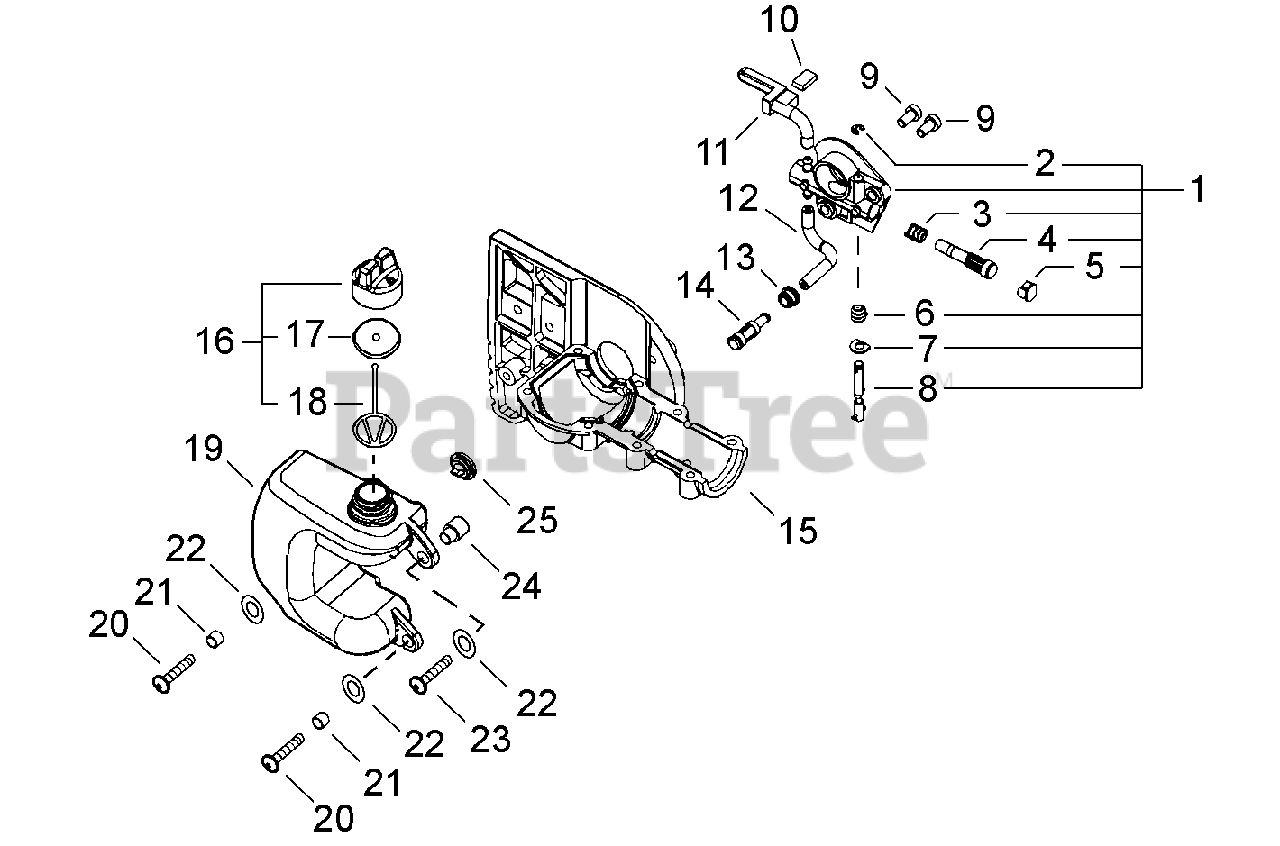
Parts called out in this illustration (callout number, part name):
1	AUTO-OILER ASSY
4	PLUNGER ASSY
5	CAP, OIL PUMP
8	ADJUSTER, OILER
9	BOLT 5×10
10	PAD, FOAM
11	PIPE, OIL OUTLET
12	PIPE, IMPULSE 3×6×75
13	GROMMET
14	FILTER, OIL
15	CASE ASSY, LOWER GEAR
16	CAP ASSY, OIL
17	GASKET, CAP
18	CONNECTOR, CAP L= 60 MM
19	TANK, OIL
20	BOLT 5×16
21	SPACER 6.2×7.8×6
22	WASHER 5.5×12×0.8
23	BOLT 5×0.8×25
24	COLLAR 6
25	VENT ASSY
